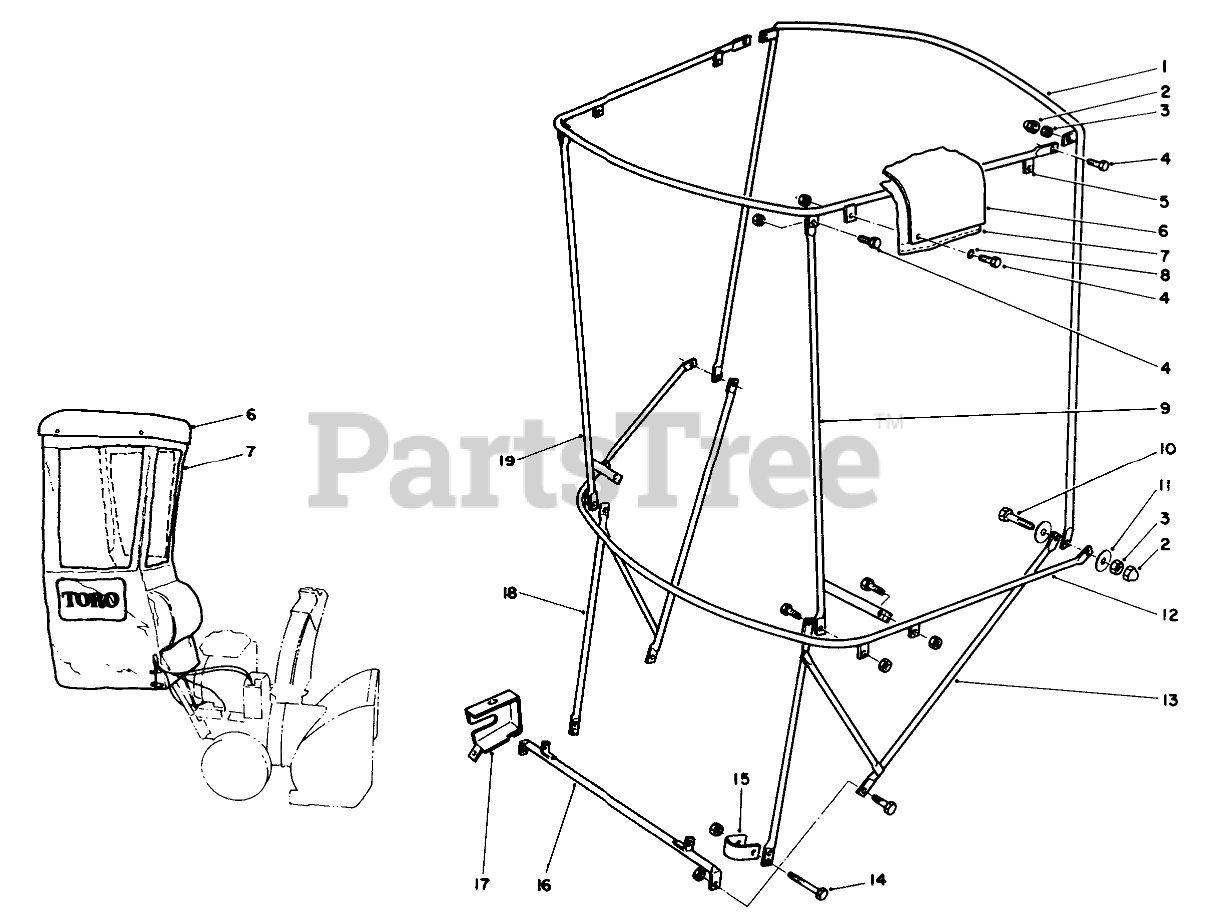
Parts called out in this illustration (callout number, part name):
1	VERTICAL BOW
2	CAPLUG
3	NUT-HEX, SIDE DEFORM
4	SCREW-HH
5	FRAME - TOP
6	Top-Plastic
7	Cover-Vinyl
8	WASHER-FLAT
9	CORNER POST - LH
10	SCREW-HH
11	WASHER-FLAT
12	HORIZONTAL BOW
13	Bracket-LH
14	SCREW-HH
15	CLAMP
16	Bracket-Base
17	COVER-LOCK, LEVER
18	BRACKET-RH
19	CORNER POST - RH
